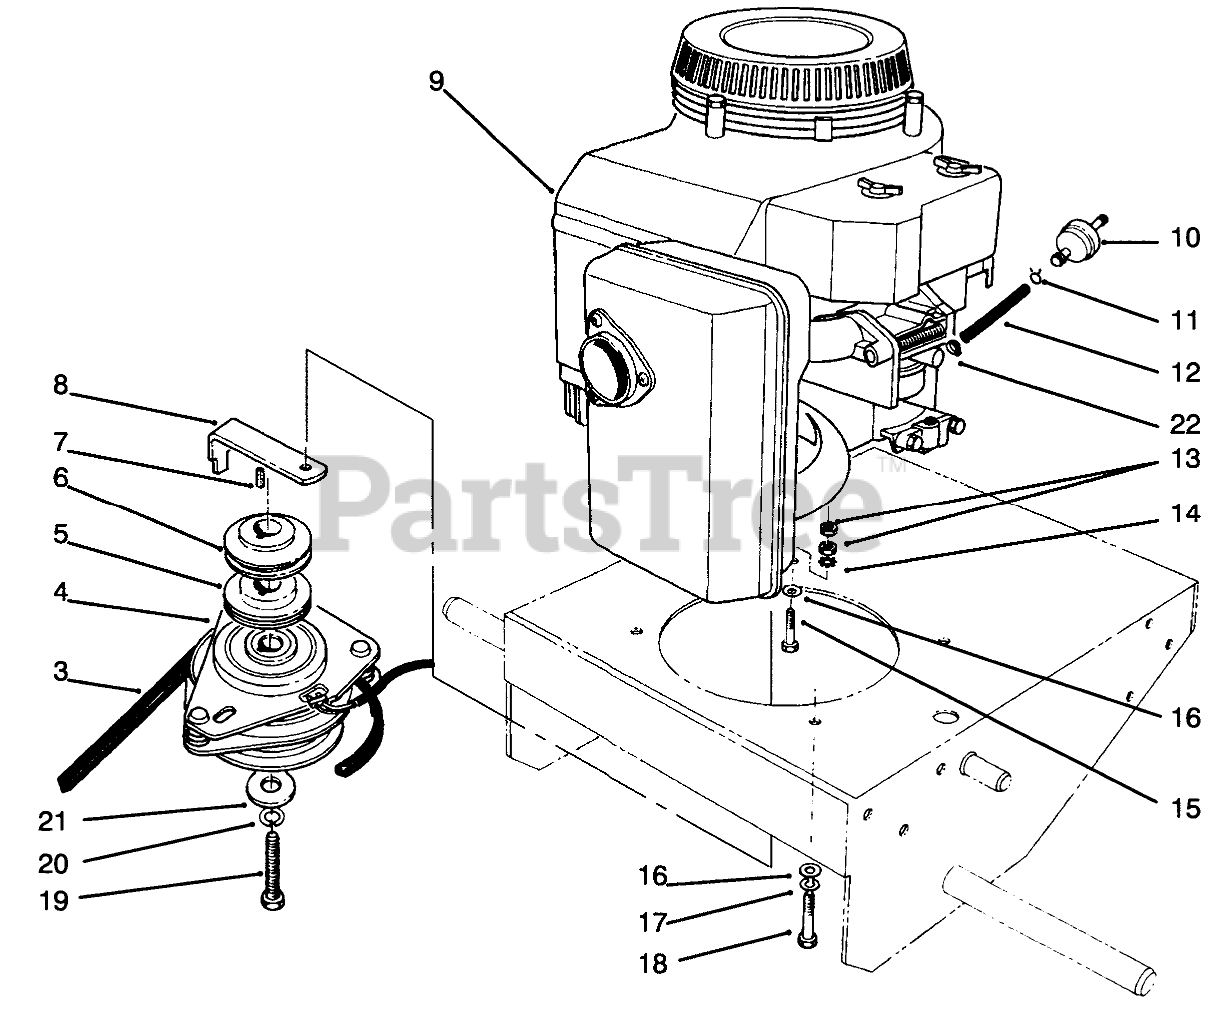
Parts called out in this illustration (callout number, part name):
3	V-BELT, DRIVE
4	CLUTCH/BRAKE
5	SHEAVE-LOWER HALF
6	SHEAVE-UPPER HALF
8	Retainer-Clutch
10	FILTER-FUEL
11	CLAMP-HOSE
12	HOSE-FUEL
13	NUT-JAM
14	WASHER-LOCK
15	SCREW (ENGINE, GROUND)
16	WASHER-PLAIN
17	WASHER-LOCK
18	SCREW-HH
19	SCREW-CLUTCH
20	WASHER-LOCK
21	WASHER-CLUTCH
22	CLAMP-WORM
